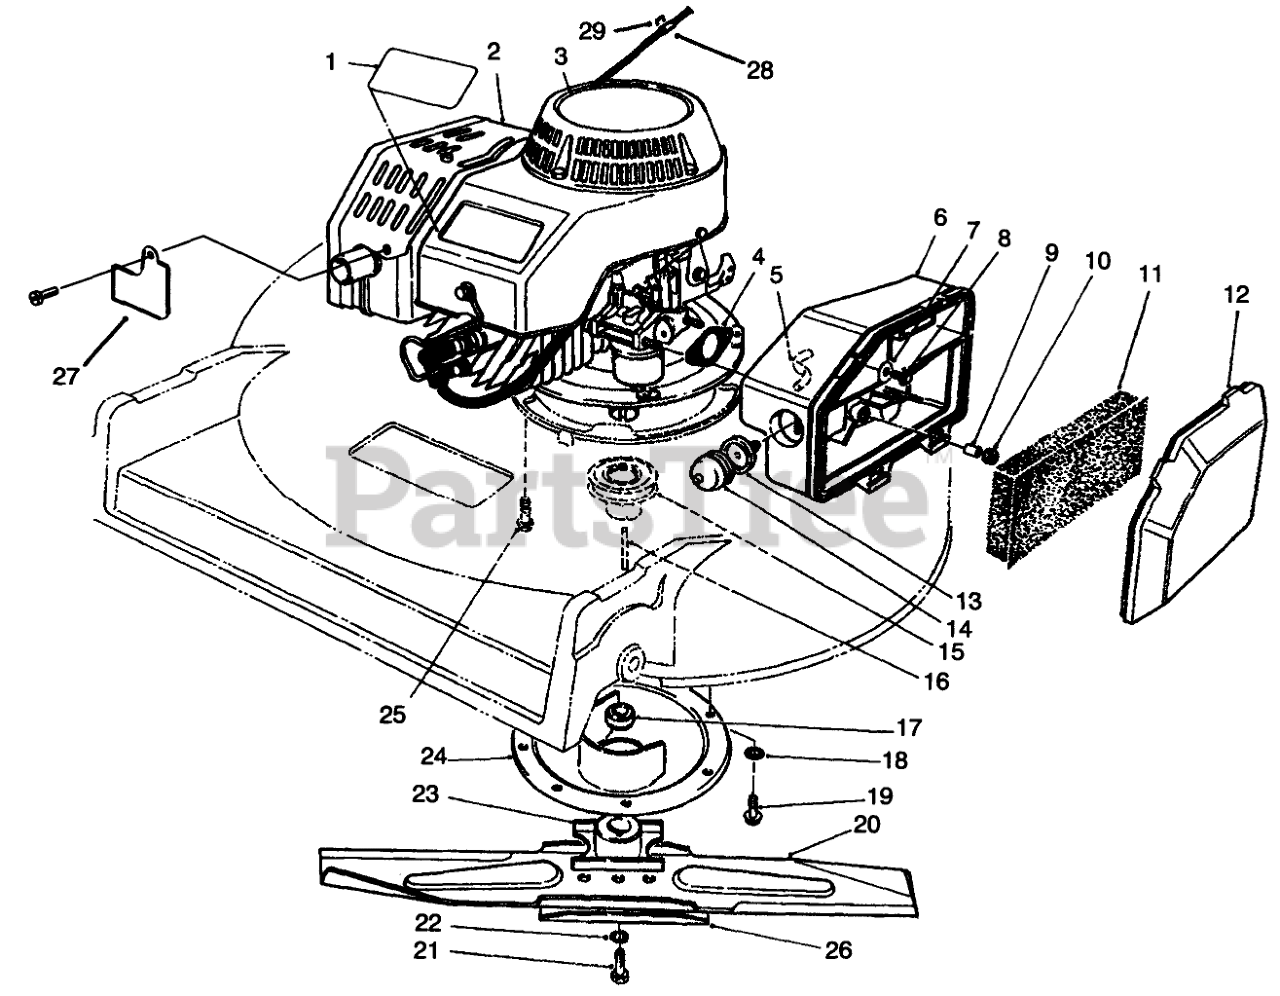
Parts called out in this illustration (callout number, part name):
1	DECAL - PROLINE
2	ENGINE ASM
3	DECAL-2 CYC RECOIL COMM
4	GASKET-AIR CLEANER
5	HOSE-PRIMER
6	BODY-AIR CLEANER
7	WASHER-FLAT
8	SCREW-HH
9	SPACER
11	ELEMENT-AIR CLEANER
12	COVER-AIR CLEANER
13	BODY-PRIMER
14	BULB-PRIMER
15	PULLEY-DRIVER
16	KEY-SQUARE
17	SPACER-BLADE RETAINER
18	WASHER-LOCK, INTERNAL
19	SCREW-HWHTF
20	Blade
21	SCREW-BLADE
22	WASHER-LOCK
23	RETAINER-BLADE
24	PROTECTOR-CRANKSHAFT
25	SCREW-HHF
26	Accelerator
27	EXTENSION-MUFFLER GUARD
29	Staple
